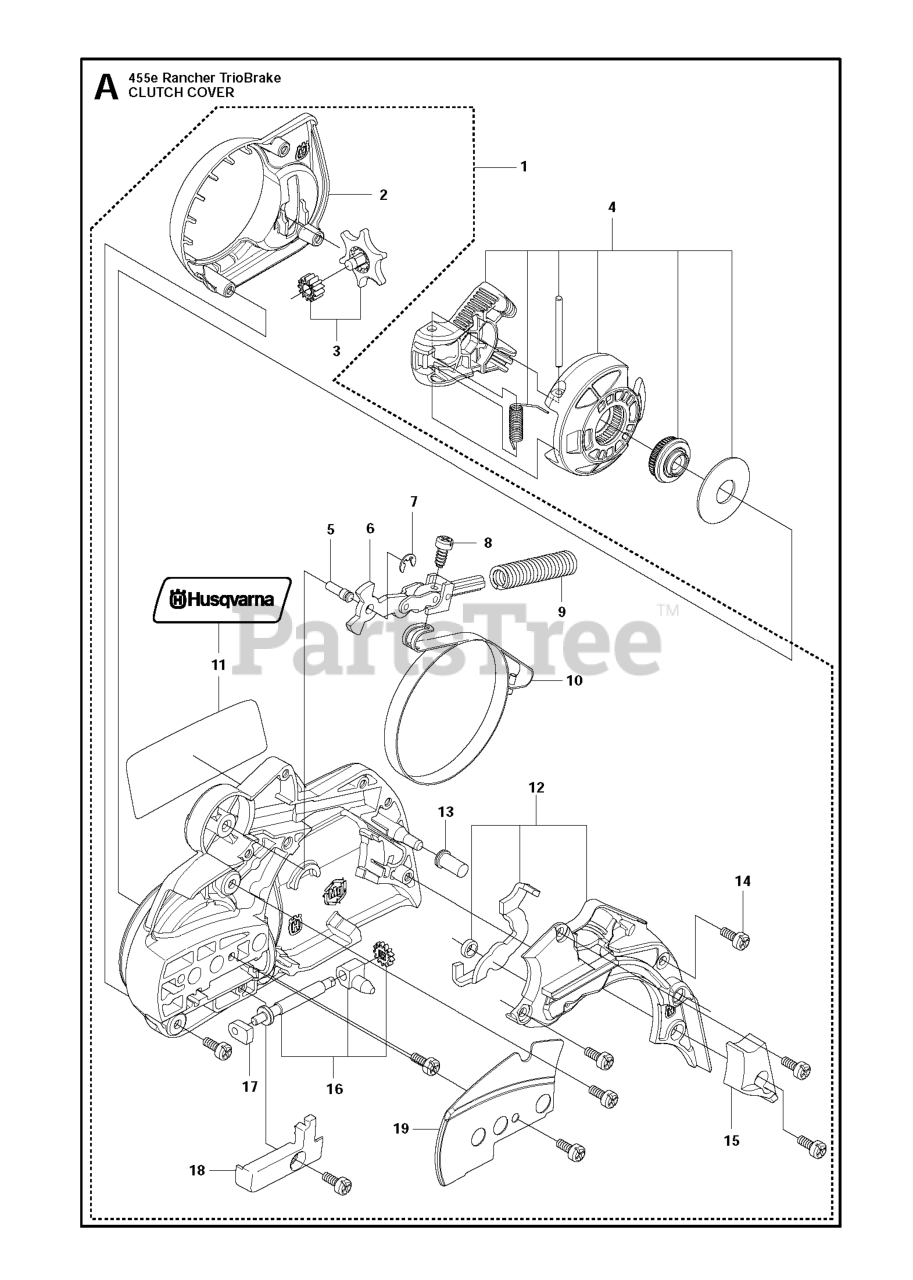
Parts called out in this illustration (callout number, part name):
1	CLUTCH COVER ASSY
2	HEAT SHIELD
3	CHAIN TENSIONER WHEEL, COMP.
4	KNOB, COMPLETE
10	BRAKE BAND
11	DECAL, CLUTCH HOUSING
12	COVER LID ASSY
15	WEAR GUARD, CHAIN
16	CHAIN TENSIONER SCREW, COMP.
17	RP BEARING SLEEVE
19	WEAR PLATE
